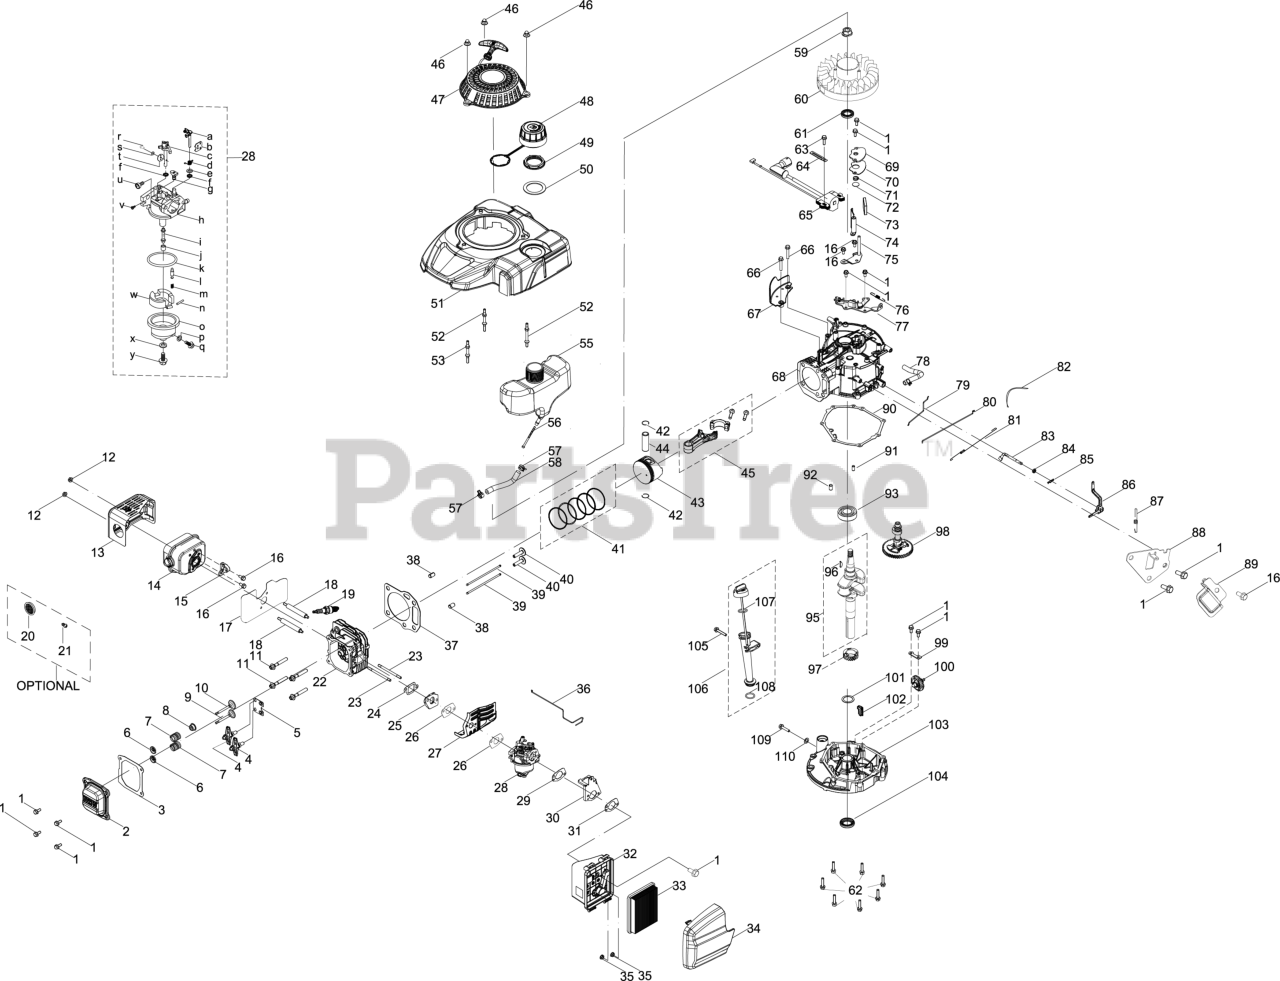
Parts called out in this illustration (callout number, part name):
1	BOLT M6-1 x 14 GR8.8
2	VALVE COVER
3	VALVE COVER GASKET
4	ROCKER ARM ASSEMBLY
5	PUSH ROD GUIDE
6	VALVE SPRING RETAINER
7	VALVE SPRING
8	INTAKE VALVE SEAL
9	EXHAUST VALVE
10	INTAKE VALVE
11	BOLT-M8 x 54
12	HEX NUT
13	MUFFLER SHIELD
14	MUFFLER ASSEMBLY
15	THERMOSTAT
16	BOLT M6-1 x 12 GR8.8
17	MUFFLER GASKET
18	STUD M6-1 x 95
19	SPARK PLUG
20	SPARK ARRESTOR
21	SCREW M3.5 x 9.5
22	CYLINDER HEAD
23	STUD M6 x 90
24	CARBURETOR INSULATOR GASKET
25	CARBURETOR INSULATOR
26	CARBURETOR GASKET
27	CARBURETOR HEAT SHIELD
28	CARBURETOR
29	AIR FILTER BRACKET GASKET
30	AIR FILTER BRACKET
31	AIR FILTER BASE GASKET
32	AIR FILTER BASE
33	AIR FILTER
33	Cub Cadet AIR FILTER
33	Genuine Factory Parts AIR FILTER
34	AIR FILTER COVER
35	HEX NUT
36	CHOKE TEMP CONTROL LINKAGE
37	CYLINDER HEAD GASKET
38	DOWEL PIN
39	PUSH ROD
40	TAPPET
41	PISTON RING SET
42	SNAP RING-PISTON PIN
43	PISTON
44	PISTON PIN
45	CONNECTING ROD ASSEMBLY
46	ACORN NUT
47	RECOIL STARTER ASSEMBLY
48	FUEL CAP W/TETHER
49	FUEL TANK NUT
50	FUEL TANK UPPER GROMMET
51	ENGINE SHROUD W/O IGNITION SWITCH
52	STARTER/SHROUD REAR STUD
53	STARTER/SHROUD FRONT STUD
55	FUEL TANK
56	FUEL FILTER
56	Genuine Factory Parts FUEL FILTER
57	HOSE CLAMP
58	FUEL HOSE
59	FLYWHEEL NUT
60	FLYWHEEL
61	CRANKSHAFT SEAL
62	BOLT-M6-1 x 28 GR8.8
63	BOLT M6-1 x 20 GR8.8
64	FLEXIBLE CLAMP
65	IGNITION COIL ASSEMBLY
66	BOLT M6-1 x 25 GR8.8
67	ENGINE BRAKE COVER PLATE
68	CRANKCASE
69	BREATHER COVER PLATE
70	BREATHER GASKET
71	BREATHER VALVE SPRING
72	BREATHER VALVE
73	BREATHER SCREEN
74	AIR VANE
75	AIR VANE BRACKET
76	ENGINE BRAKE SPRING
77	ENGINE BRAKE ASSEMBLY
78	BREATHER HOSE ASSEMBLY
79	CHOKE LINKAGE
80	THROTTLE LINKAGE
81	THROTTLE LINKAGE SPRING
82	CABLE TIE - 3 x 150
83	GOVERNOR ARM SHAFT
84	GOVERNOR SEAL
85	COTTER PIN
86	GOVERNOR ARM ASSEMBLY
87	GOVERNOR SPRING
88	COMPONENT BRACKET
89	GOVERNOR SHIELD
90	CRANKCASE COVER GASKET
91	DOWEL PIN
92	DOWEL PIN
93	BEARING
95	CRANKSHAFT
96	FLYWHEEL KEY
97	CRANKSHAFT TIMING GEAR
98	CAMSHAFT ASSEMBLY
99	GOVERNOR GEAR MOUNTING PLATE
100	GOVERNOR GEAR/SHAFT ASSEMBLY
101	THRUST WASHER
102	OIL RETURN SEAL
103	CRANKCASE COVER
104	LOWER CRANKSHAFT SEAL
105	BOLT M6-1 x 35 GR8.8
106	OIL DIPSTICK ASSEMBLY
107	O-RING
108	O-RING
109	OIL DRAIN PLUG
110	WASHER
S	Throttle Plate Lock Washer
